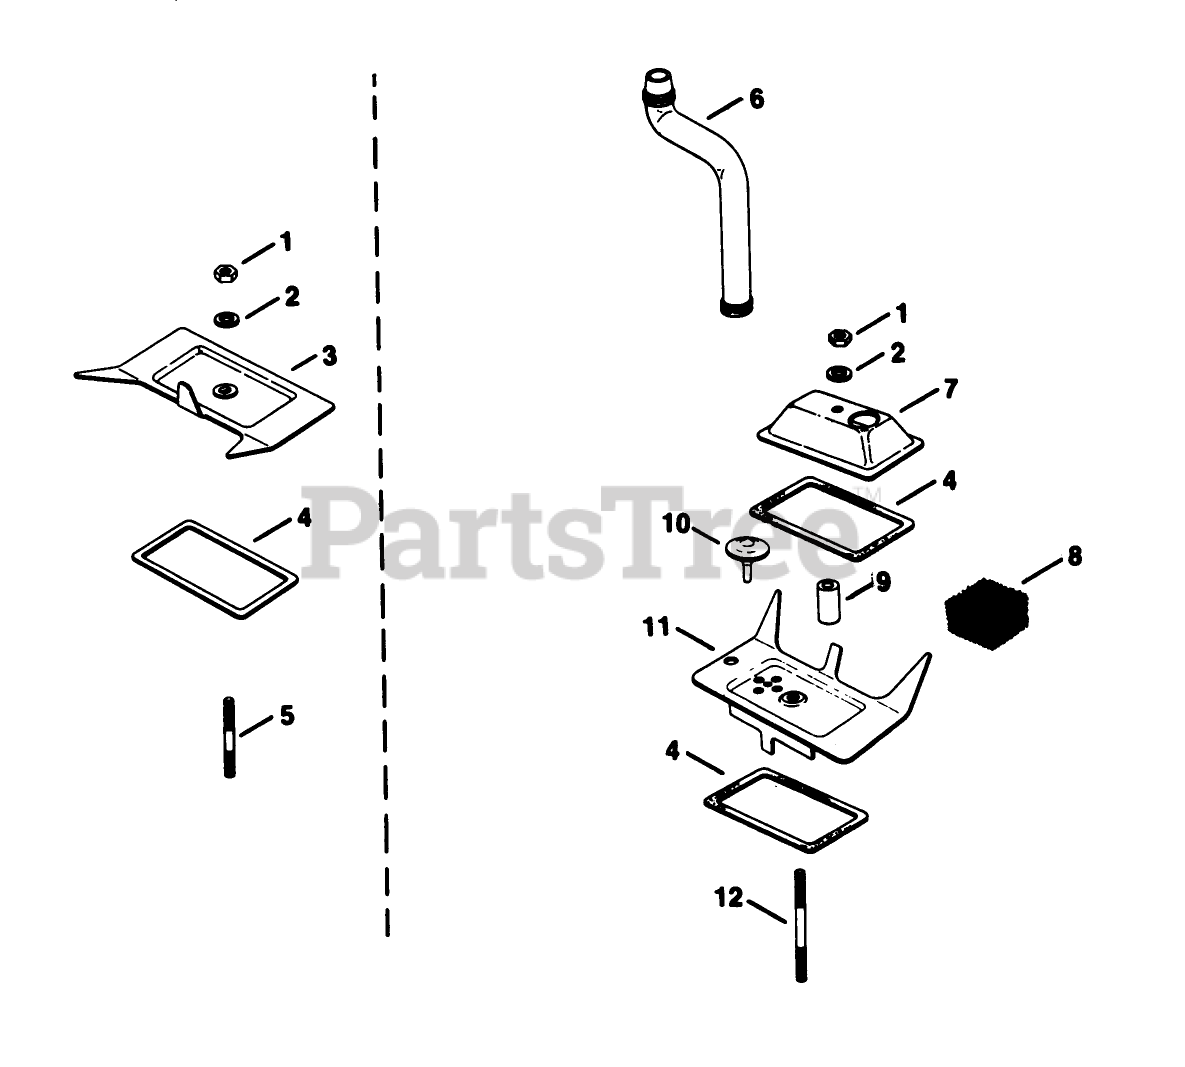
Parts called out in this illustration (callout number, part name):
2	Washer
3	Cover Cylinder Valve
4	Gasket-Cover
5	Stud-#2 Cyl Valve Cover
6	Hose-Breather
7	Cover-#1 Upper Cyl. Valve
8	Filter
9	Seal-Breather
10	Valve-Breather
11	Cover-#1 Lower Cyl. Valve
12	Stud
